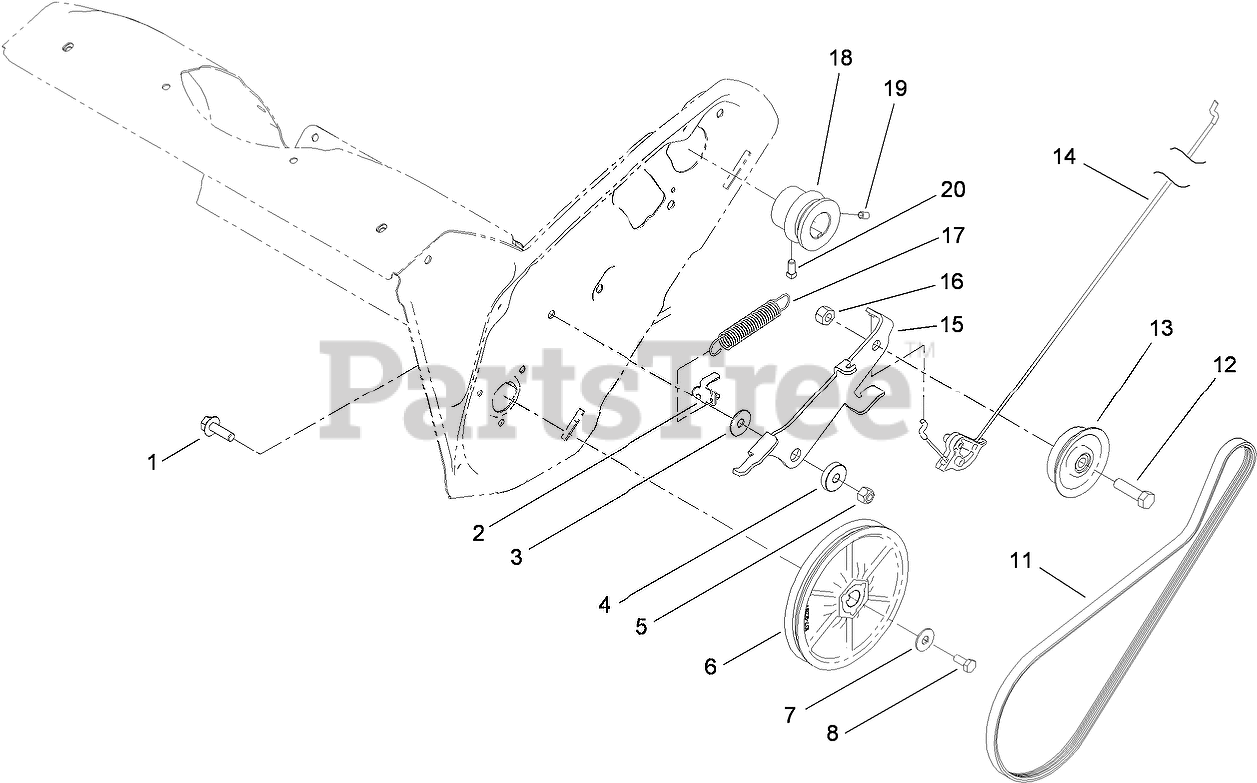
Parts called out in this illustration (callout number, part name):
1	SCREW-HHF
2	CLIP-SPRING, BRAKE
3	WASHER
4	BUSHING-PIVOT
5	NUT-LOCK, NI
6	ROTOR PULLEY ASM
7	WASHER-BELLEVILLE
8	SCREW-HH
11	BELT-DRIVE
12	SCREW-HH
13	PULLEY-IDLER
14	CABLE-CLUTCH
15	ARM-IDLER
16	NUT-LOCK, CONE
17	SPRING-EXTENSION
18	PULLEY-ENGINE
19	SCREW-HSH
20	SCREW-SQH
